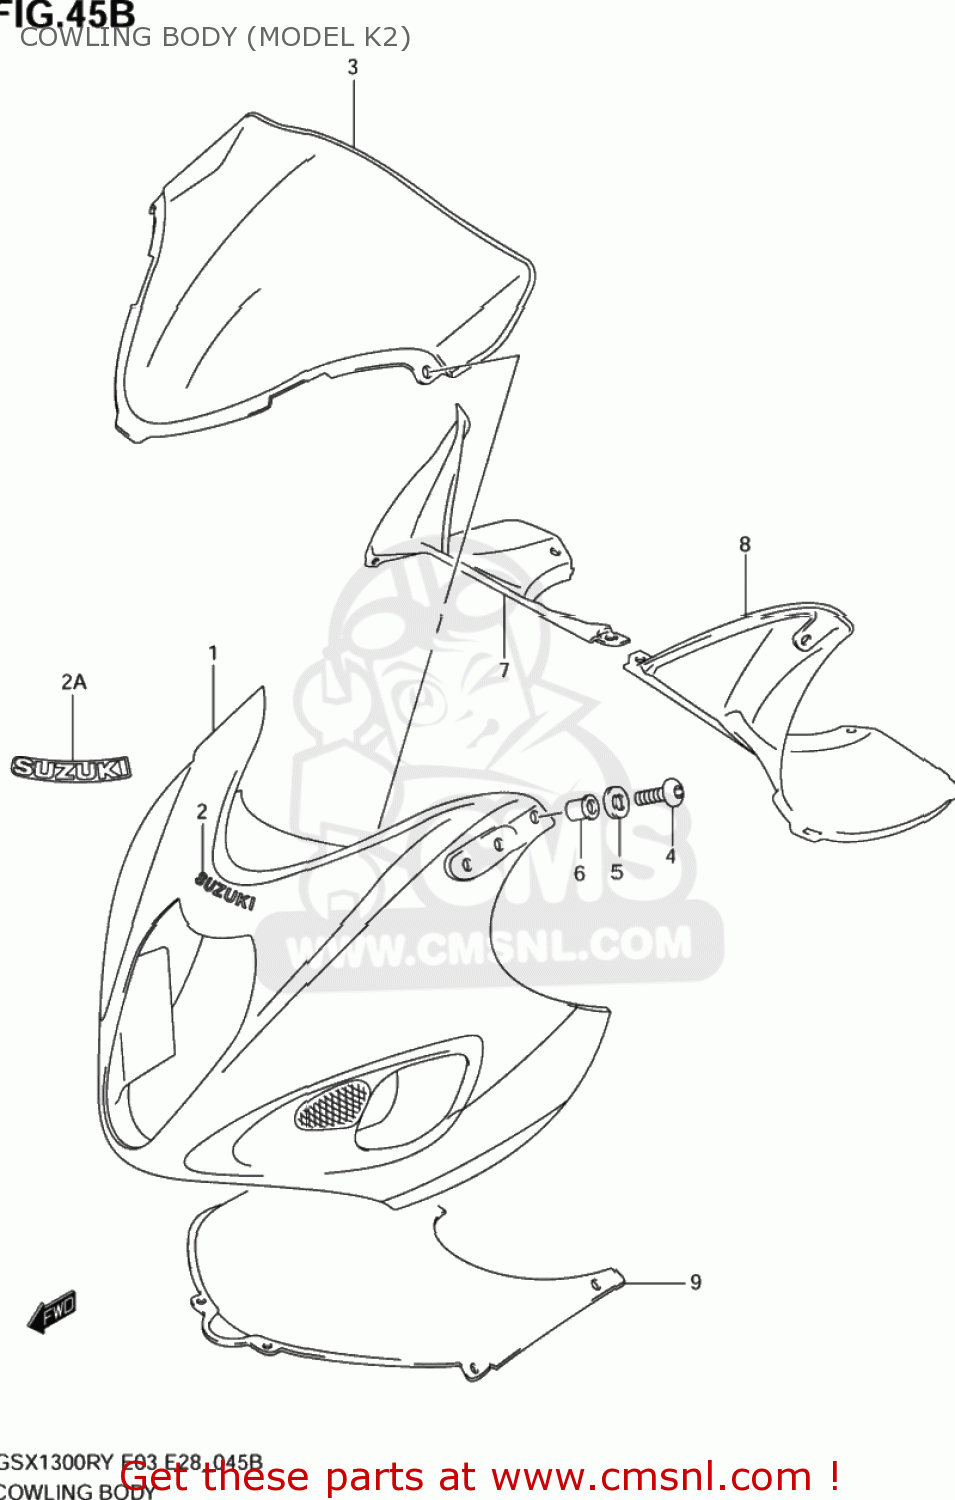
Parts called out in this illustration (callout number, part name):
1	COWLING ASSY,BODY
2	EMBLEM
2A	EMBLEM,SUZUKI
3	WINDSCREEN
4	SCREW(5X14)
5	WASHER
6	NUT
7	PANEL,UPR,R
8	PANEL,UPR,L
9	COVER,BODY COWLING
